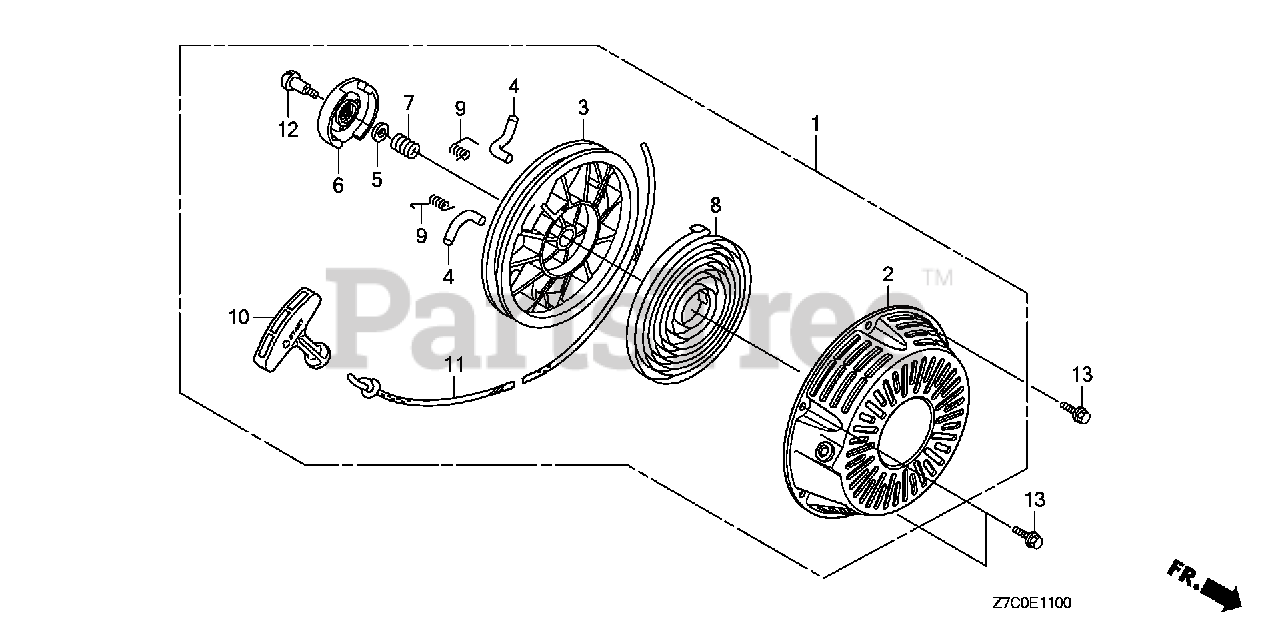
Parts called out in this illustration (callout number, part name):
1	STARTER ASSY., RECOIL *R280* (POWER RED)
1	STARTER ASSY., RECOIL *NH1* (BLACK)
2	CASE, RECOIL STARTER *R280* (POWER RED)
2	CASE, RECOIL STARTER *NH1* (BLACK)
3	REEL, RECOIL STARTER
4	RATCHET, STARTER
5	PLATE, FRICTION
6	GUIDE, RATCHET
7	SPRING, FRICTION
8	SPRING, RECOIL STARTER
9	SPRING, RETURN
10	GRIP, STARTER
11	ROPE, RECOIL STARTER
12	SCREW, SETTING
13	BOLT, FLANGE (6X10)
